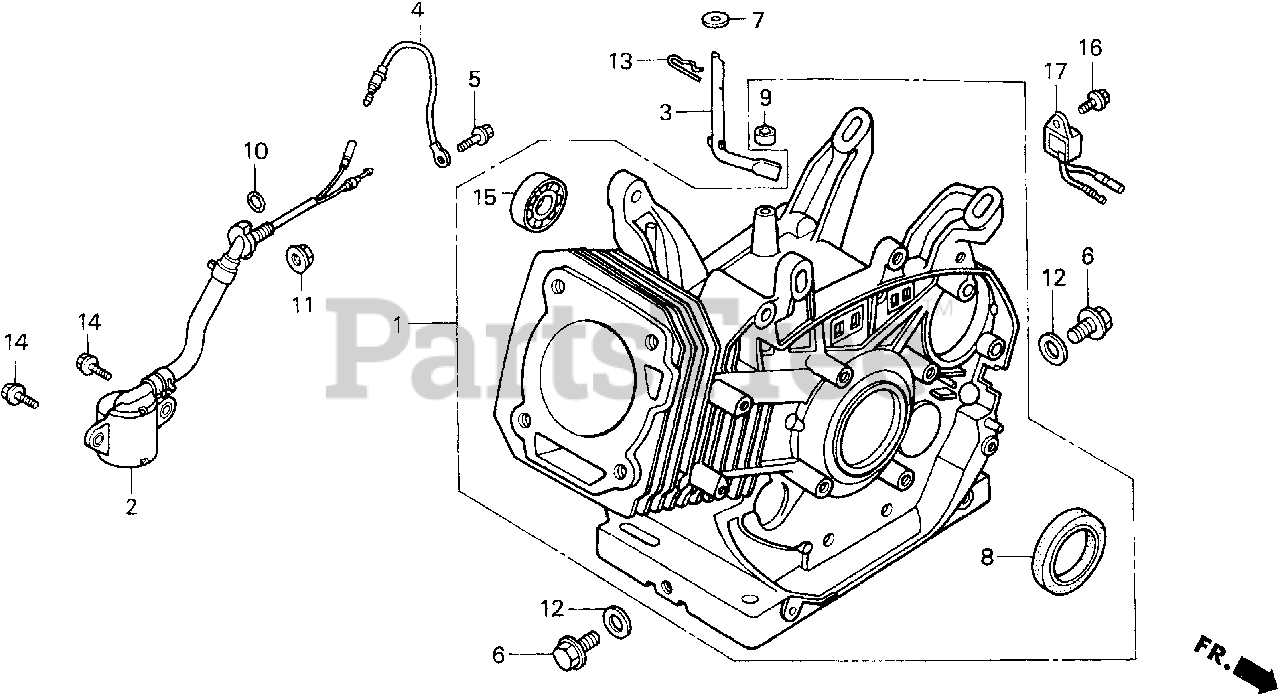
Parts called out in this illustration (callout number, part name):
1	CYLINDER ASSY. (ALERT)
2	SWITCH ASSY., OIL LEVEL
3	SHAFT, GOVERNOR ARM
4	SUB-HARNESS
5	BOLT, FLANGE (6X12) (CT200)
6	BOLT, DRAIN PLUG
7	WASHER (8.2X17X0.8)
8	OIL SEAL (35X52X8)
9	OIL SEAL (8X14X5)
10	O-RING (13.5X1.5) (ARAI)
11	NUT, FLANGE (10MM)
12	WASHER, DRAIN PLUG (12MM)
13	PIN, LOCK (10MM)
14	BOLT, FLANGE (6X12)
15	BEARING, RADIAL BALL (6202)
16	BOLT, FLANGE (6X12) (CT200)
17	ALERT UNIT, OIL
